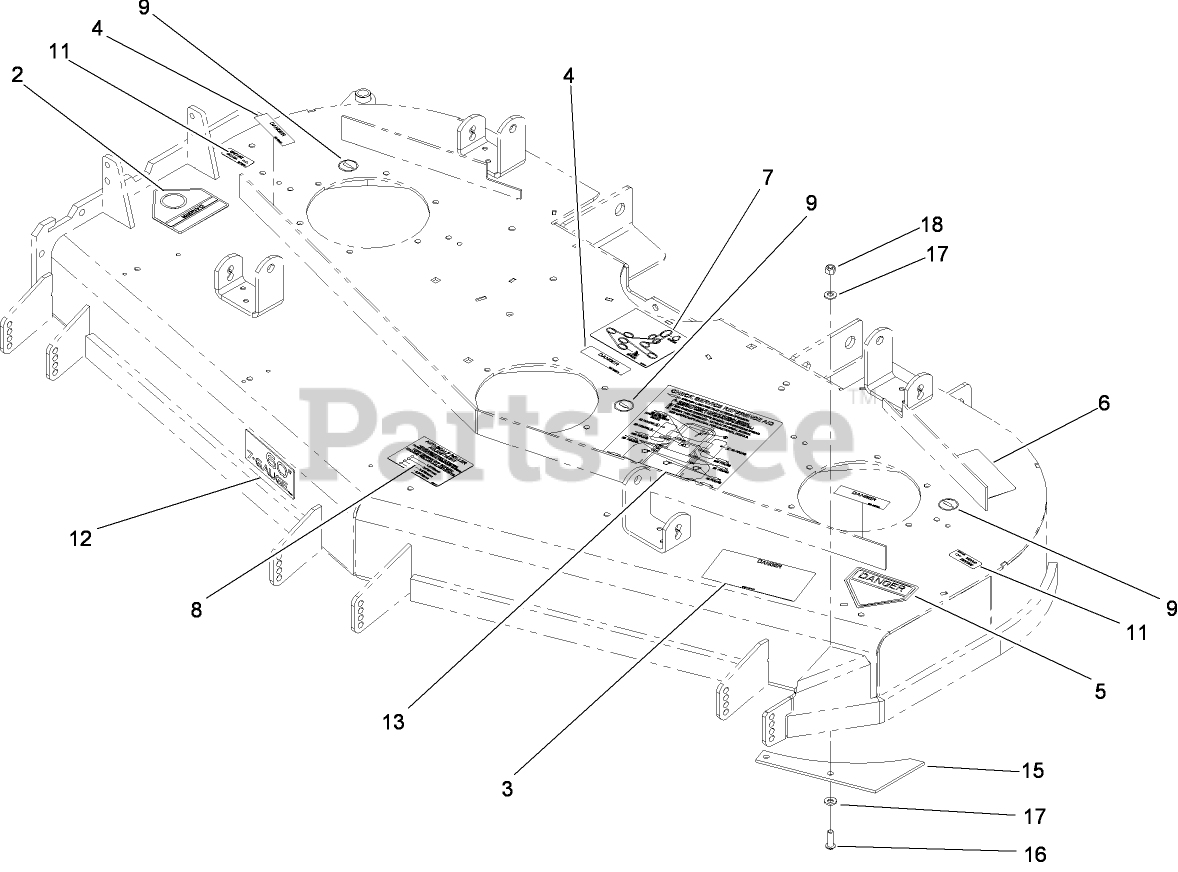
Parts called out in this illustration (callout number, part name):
2	DECAL-DANGER
3	DECAL-DANGER, THROWN OBJECT
4	DECAL-COVER, MISSING
5	DECAL-DANGER
6	DECAL-TORQUE
7	Decal-Routing, Belt
8	DECAL-SCALP, ANTI
9	DECAL-GREASE
11	Decal-Grease
13	Decal-Service, Check
15	PLATE-TURBO
16	SCREW-HSBH
17	WASHER-SPRING
18	NUT-LOCK, NI
